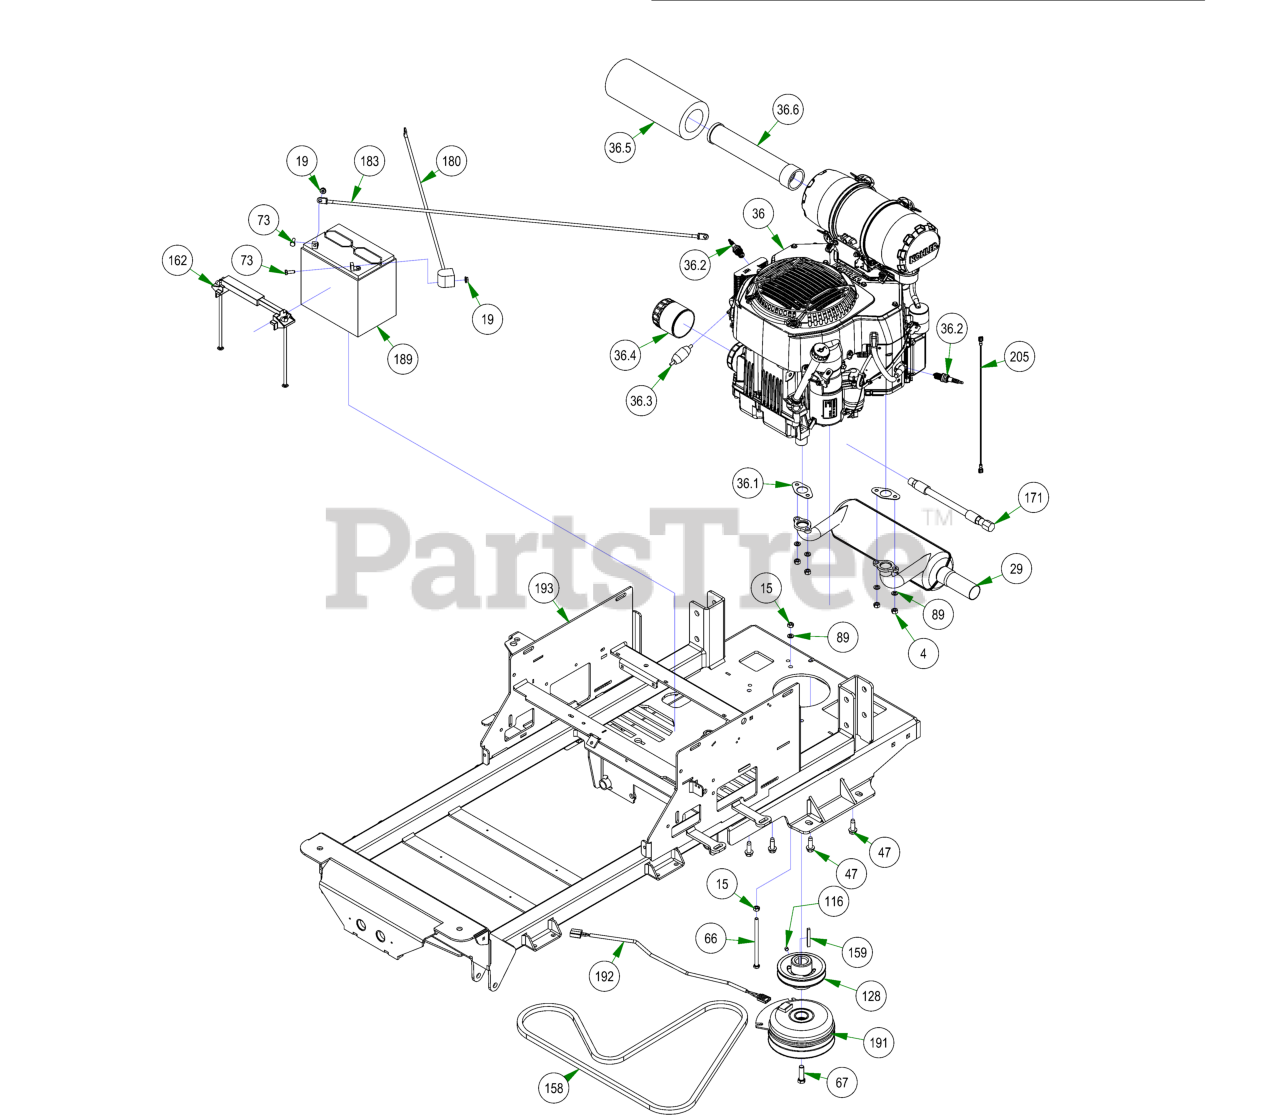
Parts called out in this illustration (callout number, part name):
4	M8-1.25 DIN 934 HEX NUT (CL.8) ZINC
15	5/16-18 HEX NUT ZINC
19	1/4-20 HEX SERRATED FLANGE NUT HARD/ZINC
29	Kohler Muffler
36	Kohler 25Hp CV-742 Command
36.1	Exhaust Gasket
36.2	Spark Plug
36.3	25/26 HP Kohler Fuel Filter
36.4	Oil Filter
36.5	Canister Air Filter- Outer
36.6	Canister Air Filter- Inner
47	3/8-16 X 1-1/8 HEX WASHER UNSLOT SERRATED (TRI-LOB) TRS ZINC YELLOW
66	5/16-18 X 5-1/2 HEX CAP SCREW (GR.5) ZINC
67	7/16-20 X 1-1/2 HEX CAP SCREW (GR.8) w/ Patch
73	1/4-20 X 3/4 HEX CAP SCREW (GR.5) ZINC
89	5/16 SPLIT LOCKWASHER ZINC
116	5/16-24 X 1/4 SOCKET SET SCREW (CUP PT) PLAIN
128	4 3/4 Motor Pulley
158	75.8" Pump Belt
159	1/4 X 2 SQ MACHINERY KEY 1018 STL PLAIN
162	Hold Down Assembly
171	Oil drain Hose
180	24 inch Black Cable – MZ/ZT
183	36" Red Battery Cable
189	SP-35 Battery
191	Clutch Assembly
192	Clutch Pigtail
193	2022 Maverick Frame - Painted
205	Compact Outlaw/Honda Starter Jumper Wire
